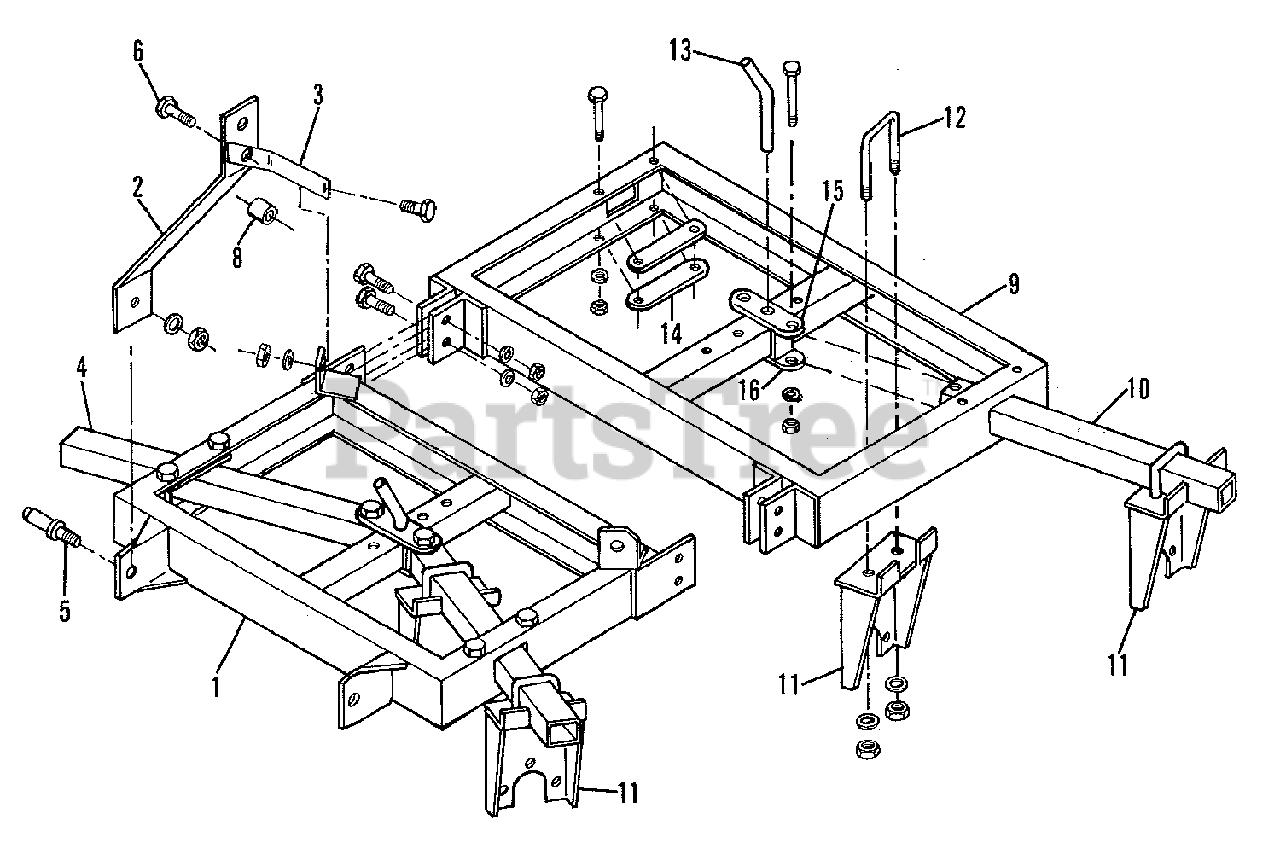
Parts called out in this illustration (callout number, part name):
1	FRAME ASSEMBLY, Front
2	FRAME, Tower
3	CAPSCREW, 5/8NC x 4
3	CAPSCREW, 5/8NC x 2
3	LOCKWASHER, 5/8
4	BAR, Gang, Front (For 4 Blades)
4	BAR, Gang, Front (For 5 Blades)
5	PIN, Link (Cat. I)
5	LOCKWASHER, 7/8
6	PIN, Hitch, Upper
8	SPACER, Tower Arm
9	FRAME ASSEMBLY, Rear
9	CAPSCREW, 3/4NC x 3
9	LOCKWASHER, 3/4
10	BAR, Gang, Rear
11	HANGER, Gang (For Sealed Bearings)
12	U-BOLT, Gang Hanger
12	LOCKWASHER, 1/2
13	PIN, Gang Adjusting
14	SHIM, Gang Bar
14	CAPSCREW, 1/2NC x 5-1/2
14	LOCKWASHER, 1/2
15	BRACKET ASSEMBLY, Sliding, Upper
15	CAPSCREW, 5/8NC x 5
15	LOCKWASHER, 5/8
16	BRACKET, Sliding, Lower
17	DECAL (Allis-Chalmers)
18	DECAL (44 Model Identification)
